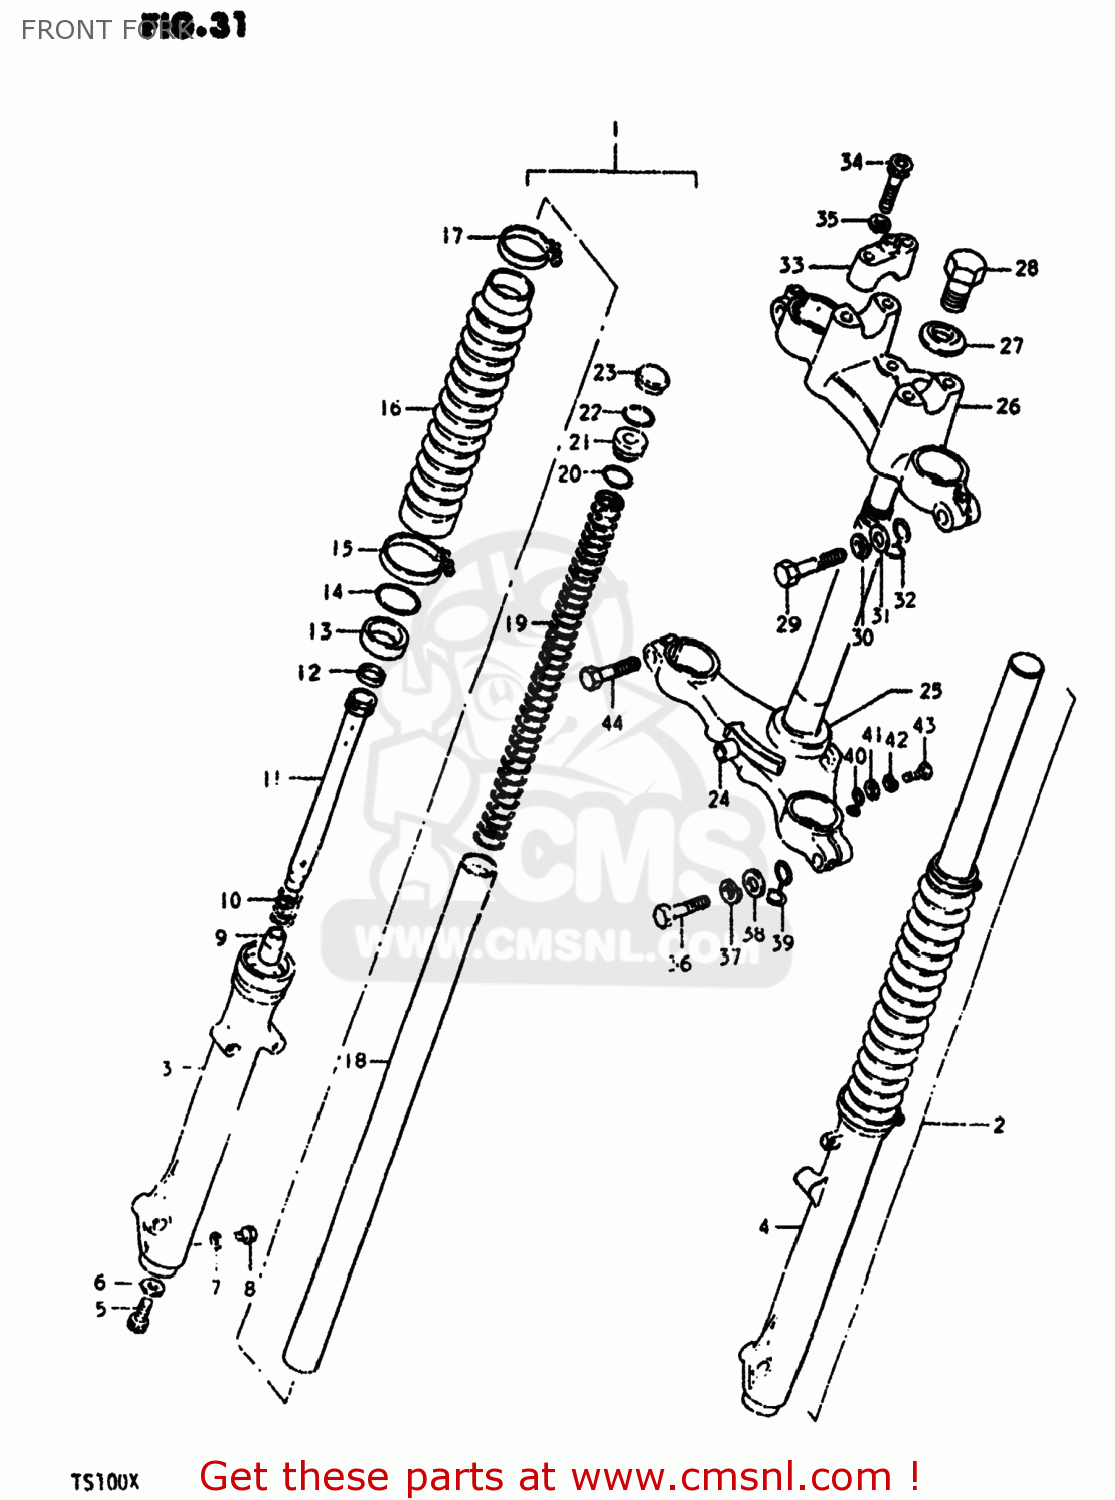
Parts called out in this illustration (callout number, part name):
1	DAMPER ASSEMBLY,RIGHT
2	DAMPER ASSEMBLY,LEFT
3	TUBE,FORK,OUTER,RIGHT
4	TUBE,FORK,LEFT,OUTER
5	BOLT(8X27)
6	GASKET (NAS)
7	GASKET,DRAIN,PLUG (NAS)
8	BOLT(6X8)
9	PIECE,OIL LOCK
10	SPRING,FORK REBOUND
11	CYLINDER,FRONT FORK
12	RING
13	OIL SEAL,FRONT FORK
14	CIRCLIP,FORK OIL SEAL
15	CLAMP
16	BOOT
17	BAND,FRONT FORK COVER BOOT
18	TUBE,FORK,INNER
19	SPRING,FRONT FORK
20	O RING
21	SEAT,SPRING
22	RING,STOPPER
23	CAP,FRONT FORK
